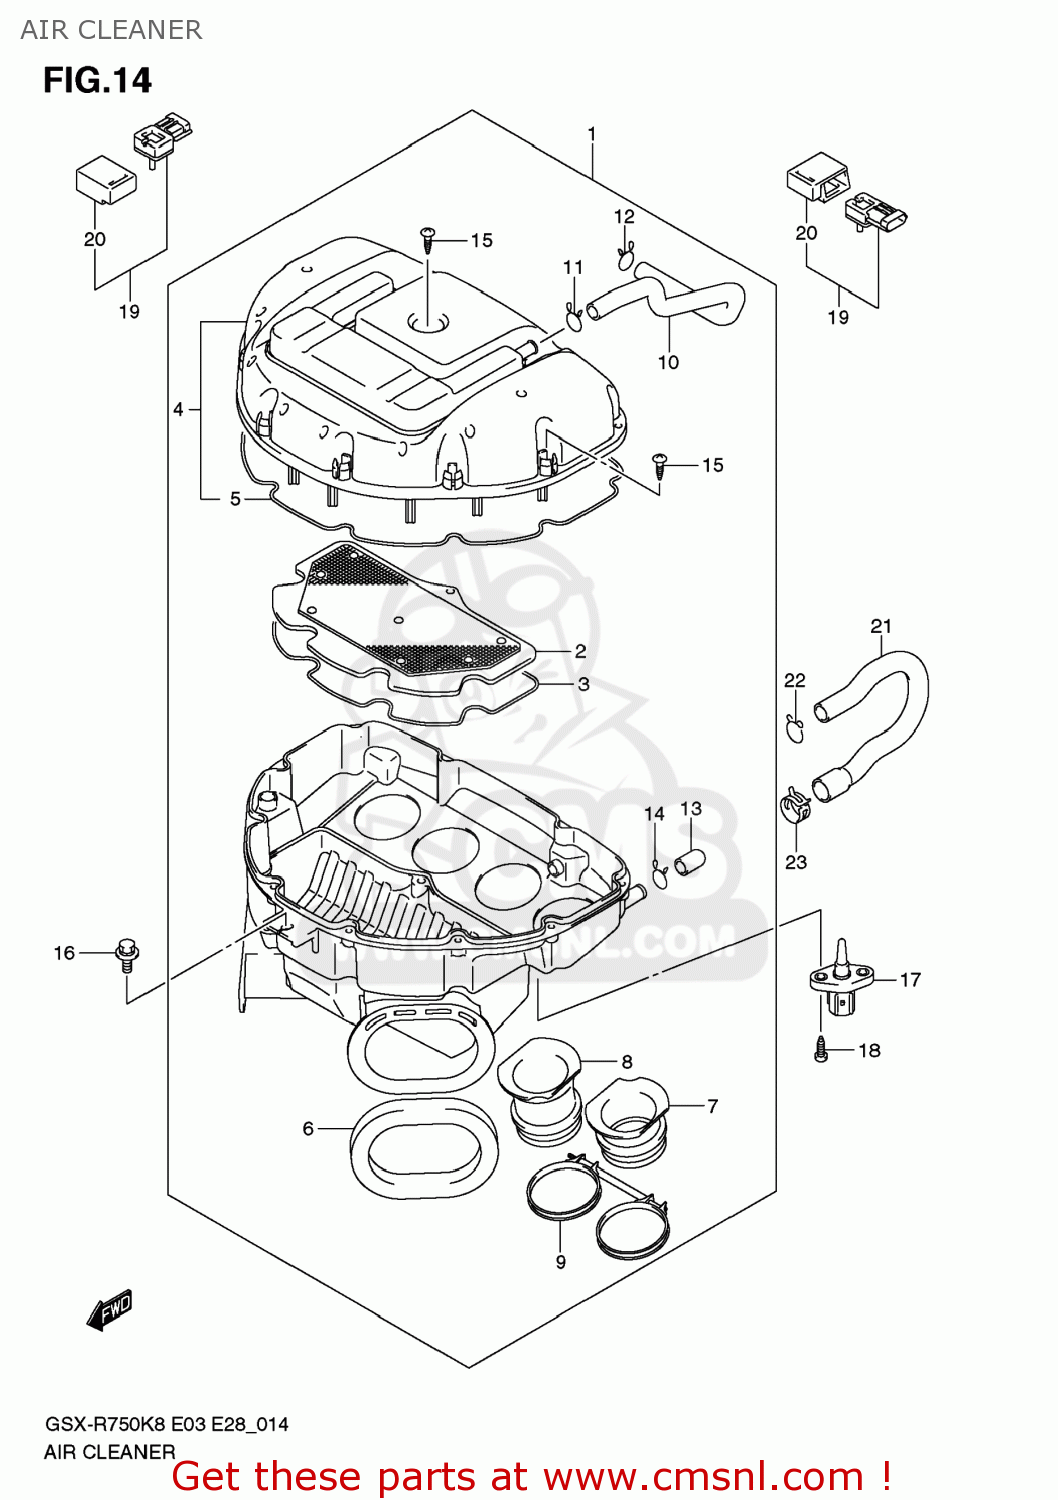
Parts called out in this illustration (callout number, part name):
1	CLEANER ASSY,AIR
2	FILTER ASSY
3	GASKET,CASE (NAS)
4	CAP,AIR CLEANER
5	GASKET,CAP (NAS)
6	CUSHION,DUCT
7	TUBE,OUTLET
8	TUBE,OUTLET
9	CLAMP,INTAKE PIPE
10	TUBE,BREATHER
11	CLIP
12	CLIP
13	PLUG
14	CLIP
15	SCREW
16	BOLT(6X16)
17	SENSOR,AIR TEM
18	SCREW
19	SENSOR,AIR PRESSURE
20	COVER
21	HOSE,ISC VALVE
22	CLIP
23	CLIP
